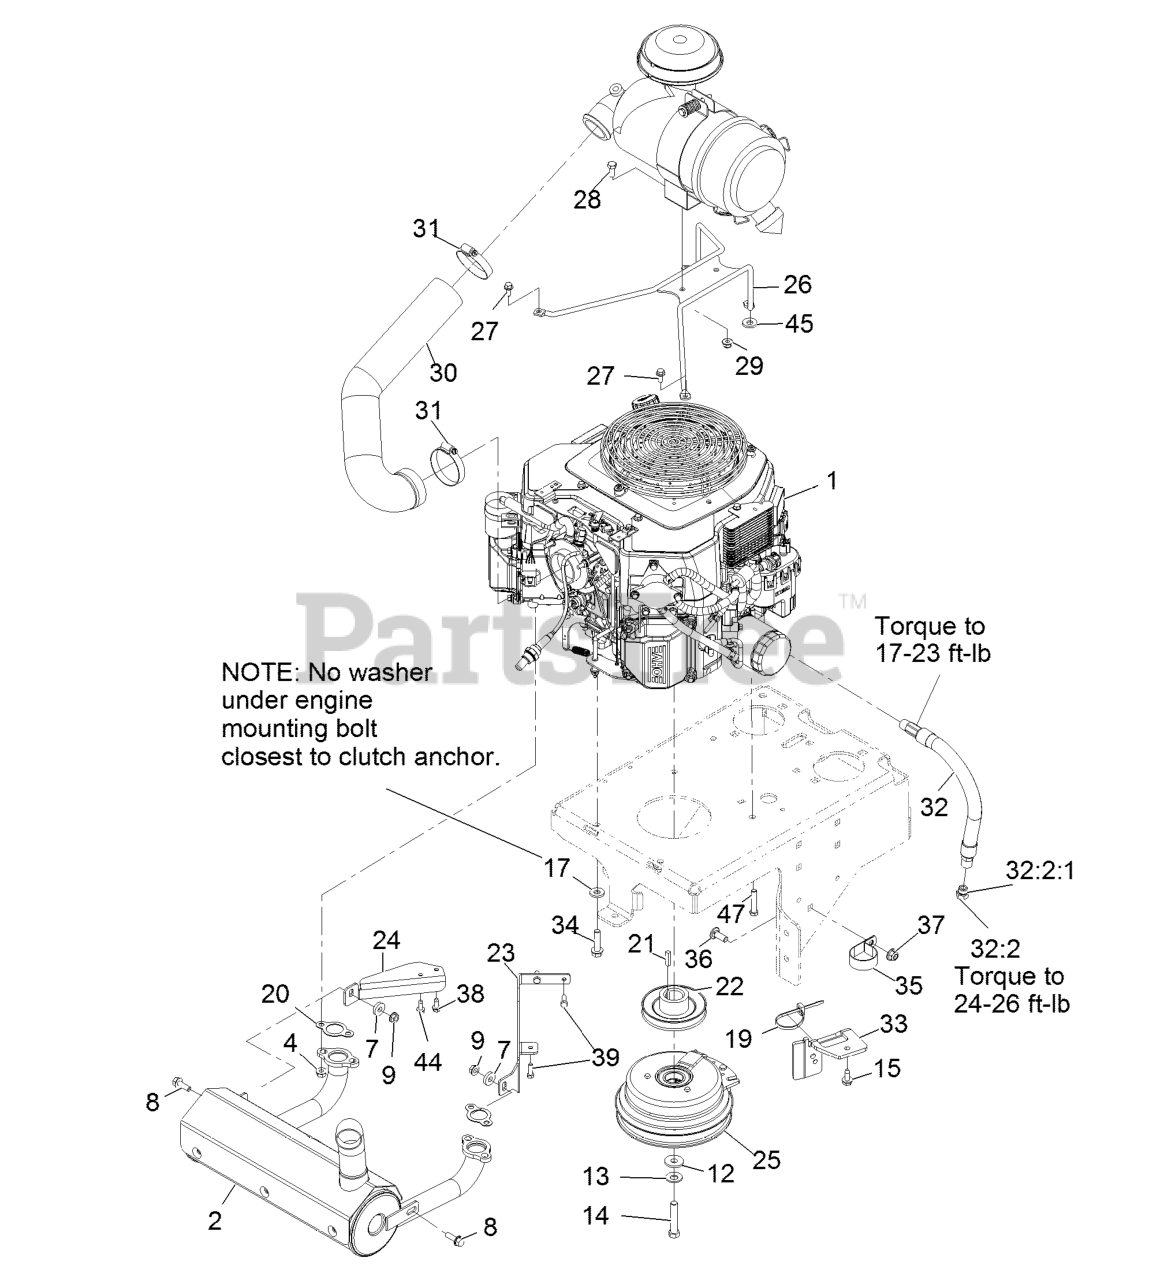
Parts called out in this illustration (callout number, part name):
1	Engine, Kohler
4	NUT-FLANGE
8	SCREW-HHF
12	WASHER
13	WASHER-SPRING
14	SCREW-HH
15	Screw-HWH 5/16-18 X 3/4 Tf
17	WASHER-BELLEVILLE
19	TIE-CABLE
20	GASKET-EXHAUST
23	BRACKET-MUFFLER, LH
24	BRACKET-MUFFLER, RH
25	CLUTCH-200 FT-LB, 1.125 B
26	MOUNT-CLEANER, AIR
27	SCREW-HHF
28	SCREW-HH
29	NUT-HF, NI
30	HOSE-INTAKE, AIR
31	CLAMP-HOSE
32	OIL DRAIN HOSE ASM
32:2:1	O-RING
32:2:2	PLUG-HH
33	BRACKET-ANCHOR, CLUTCH
34	SCREW-HWH
35	CLAMP-R
36	SCREW-CARR
37	NUT-HF, NI
38	SCREW-HWHTF
39	SCREW-HH M6-1 X 20Mm W/Patch
44	SCREW-HWHTF
45	WASHER-PLAIN
47	SCREW-HH
